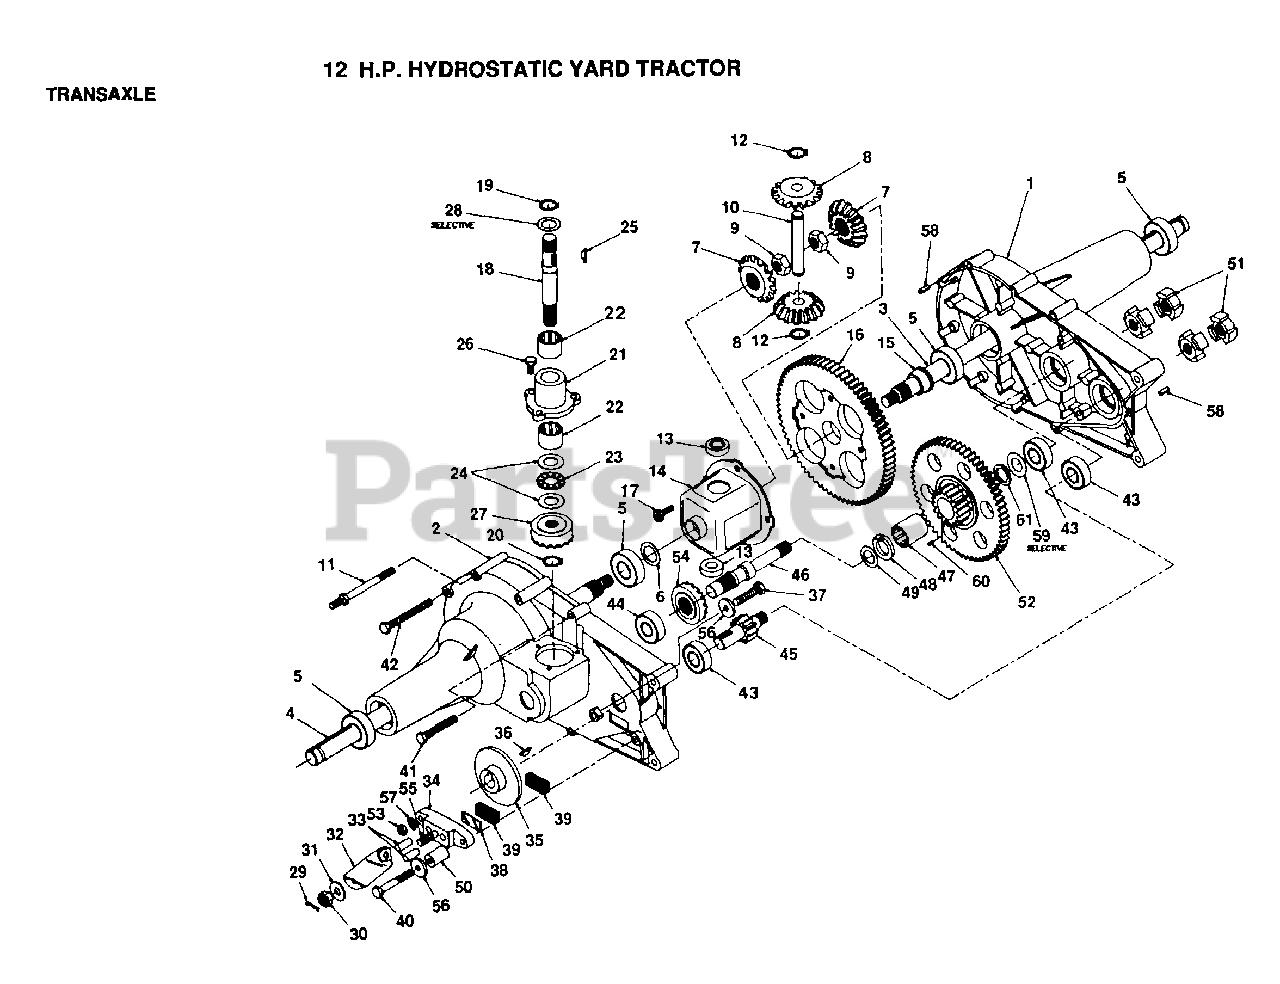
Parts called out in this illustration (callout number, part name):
1	HSG HALF LH-44077
2	HSG HALF RH-44076
3	AXLE LH -44273
4	AXLE RH-44272
5	BEARING.44121.AGR
6	WASHER -44008
7	GEAR MITER -44096
8	GEAR MITER -44097
9	NUT -44133
10	SHAFT CROSS
11	SCREW-STUD -44271
12	SNAP RING -44146
13	"THRUST, BEARING -44128"
14	HOUSING.ASM.DIFF.-62590
15	"FLANGE, BEARING-44129"
16	GEAR
17	BOLT -44126
18	SHAFT INPUT-44270
19	SNAP RING -44145
20	RET RING (44144)
22	"NEEDLE, BEARING 44099"
23	BEARING.NEE.44139
24	WASHER-44109
25	KEY.44136.HYDRO
26	SCREW
28	WASHER -44125
29	PIN COTTER -44101
30	NUT -44142
31	WASHER FLAT -44130
32	ARM BRAKE 23710
33	PIN BRAKE ACTUATO -44127
34	BRAKE YOKE
35	DISC BRAKE -(44090)
36	KEY -44143
37	SCREW -44277
38	PLATE PUCK -44134
40	SCREW -44300
41	SCREW -44123
42	SCREW -44124
43	"BALL, BEARING -44147"
44	"BALL, BEARING -44232"
45	SHAFT PINION 44083
46	SHAFT DRIVE-44080
47	NEEDLE BEARING -44342
48	THRUST.BRONZE -44343
49	WASHER-44151
50	SPACER -23711
51	COUPLING- 44084
53	NUT -43178
54	PINION-DR.44079
55	BOLT SQ HD
56	WASHER -44278
57	WASHER -44137
58	PIN ROLL-44269
60	DOWEL PIN -44346
61	SEAL GREASE -44394
